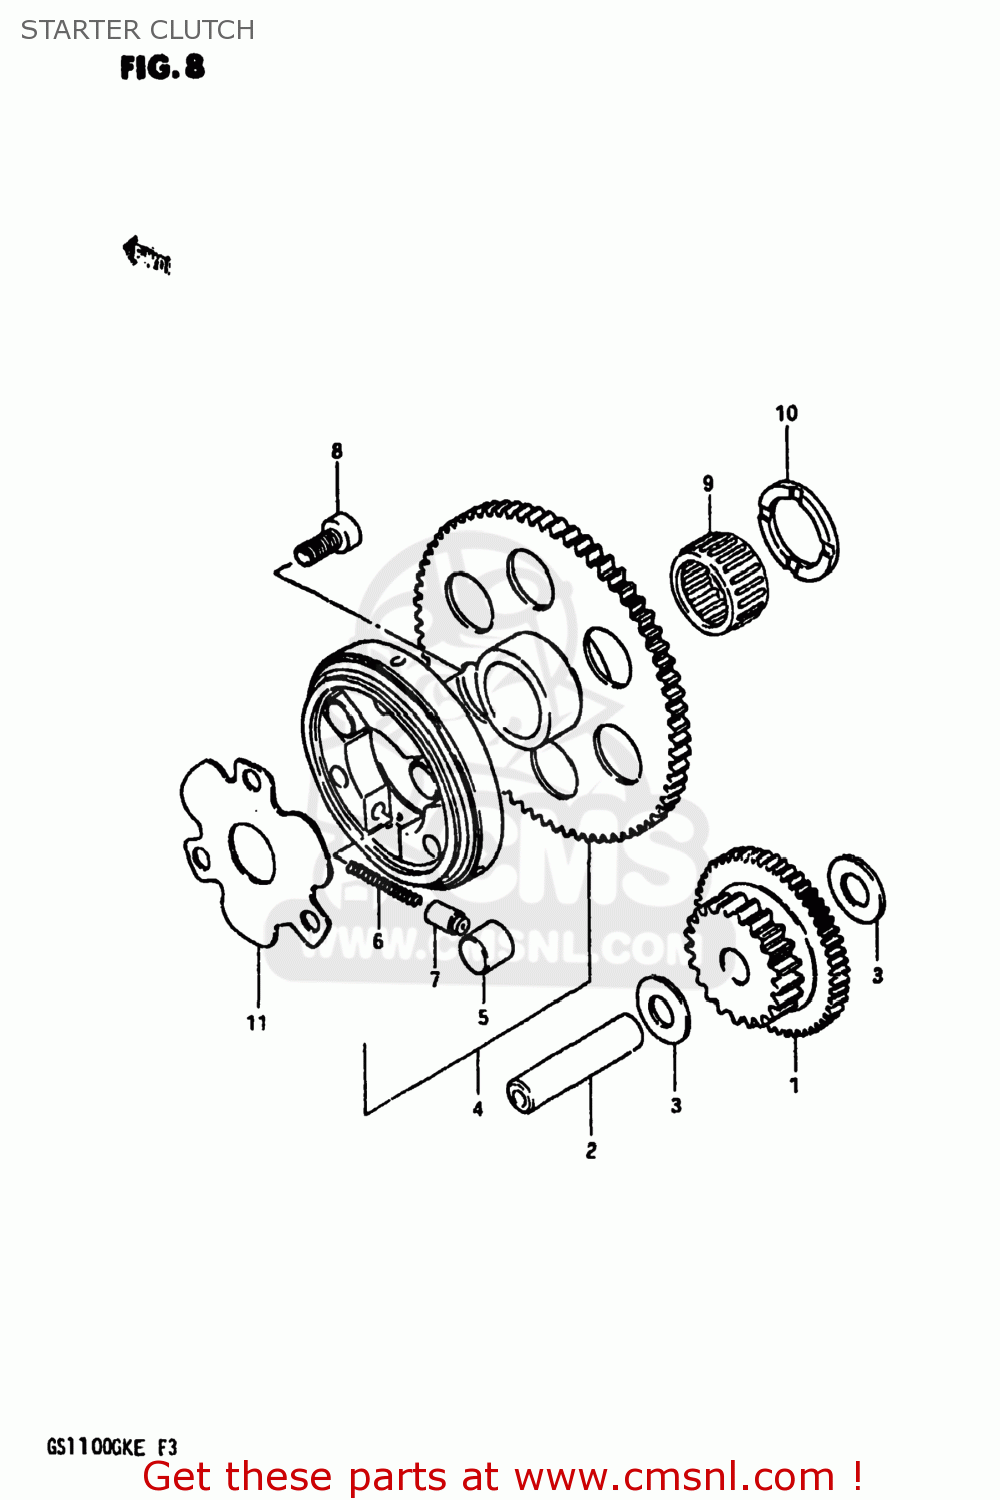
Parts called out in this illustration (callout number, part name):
1	GEAR,STARTER IDLE
2	PIN(7.4X13X56)
3	WASHER(13.3X25X0.85)
4	CLUTCH SET,STARTER
5	PIN(14X13)
6	SPRING
7	PIECE,PUSH
8	BOLT
9	ROLLER BEARING (25X31X2
10	WASHER(25X38X2.5)
11	SHIM,STARTER CLUTCH HUB
